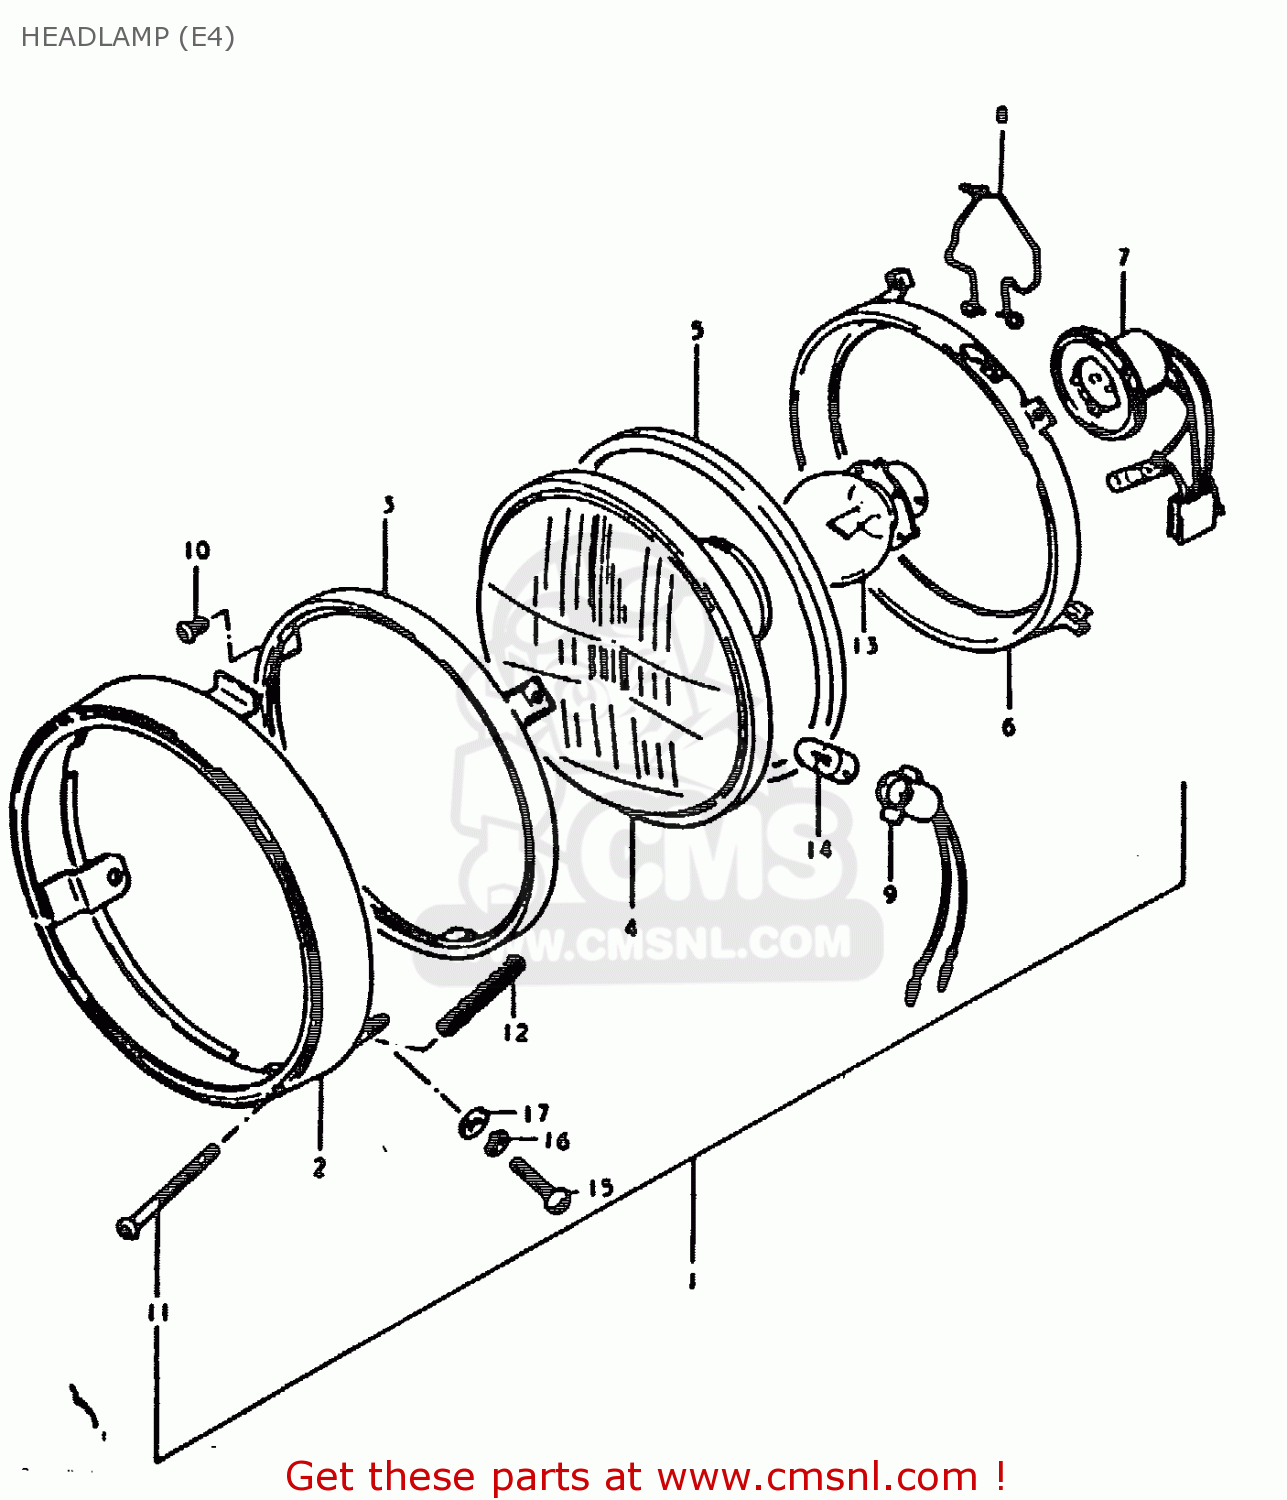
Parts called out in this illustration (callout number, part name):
1	HEADLAMP ASSY
2	RIM
3	RING
4	UNIT
5	GASKET
6	RING, MOUNTING
7	SOCKET
8	CLAMP,HEADLAMP
9	SOCKET
10	SCREW
11	SCREW,HEADLAMP ADJUST
12	SPRING,ADJUSTING
13	BULB (6V,25/25W)
14	BULB (6V,4W)
15	SCREW
16	LOCK WASHER
17	WASHER
